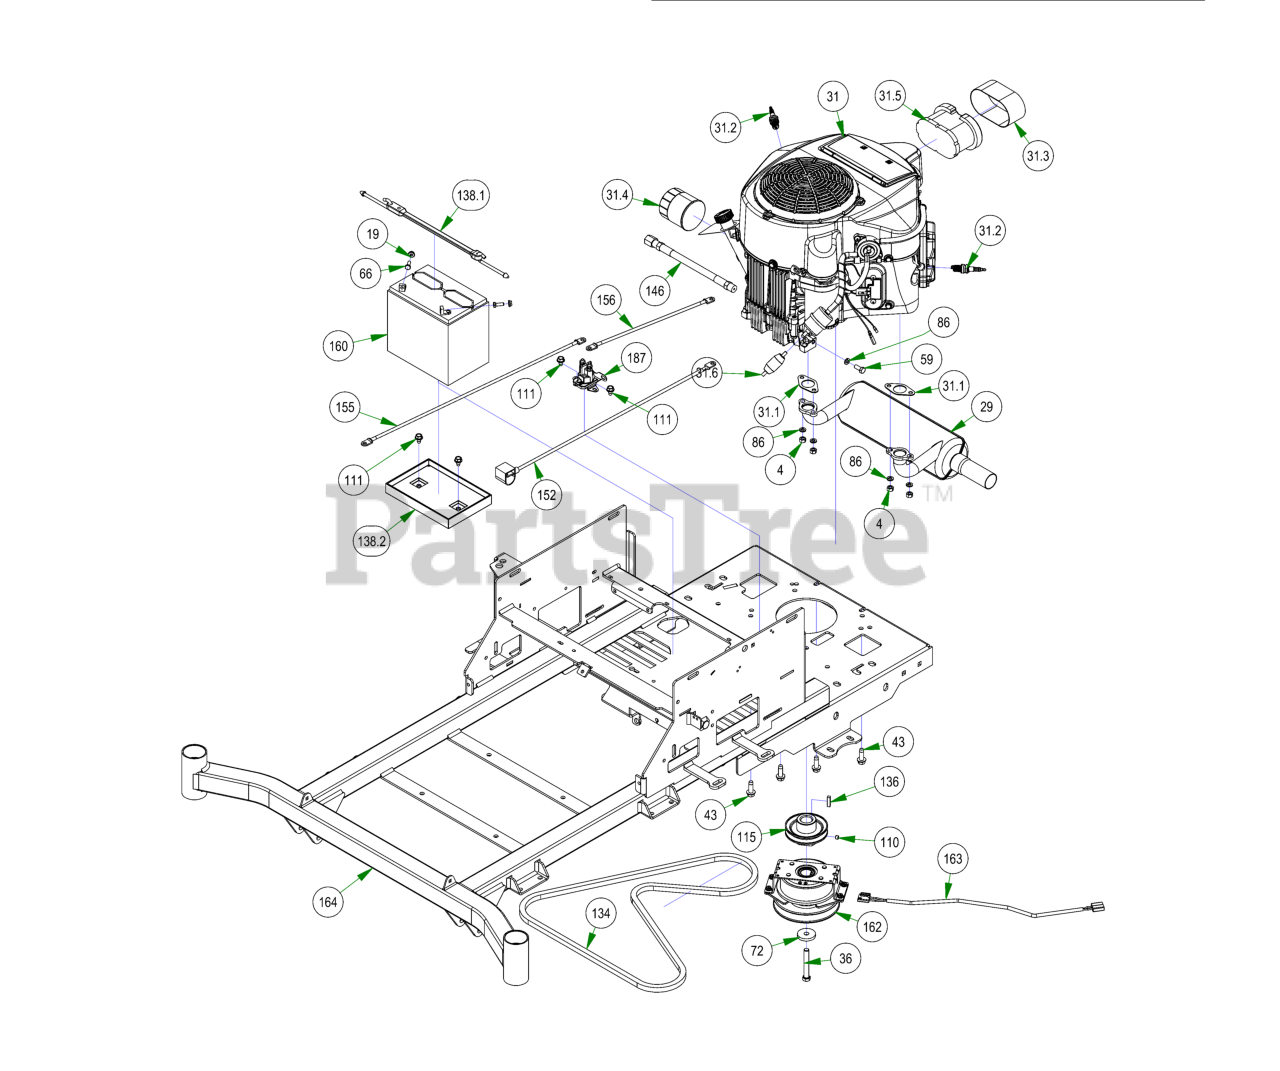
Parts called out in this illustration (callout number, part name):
4	M8-1.25 DIN 934 HEX NUT (CL.8) ZINC
19	1/4-20 HEX SERRATED FLANGE NUT HARD/ZINC
29	Kawasaki Muffler 1251
31	Kawasaki FR691 29.5HP
31.1	Exhaust Gasket
31.2	Spark Plug - Kawasaki
31.3	Air Filter Pre-Cleaner for KAW
31.4	22-26 Kaw Oil Filter FR Engine
31.5	Kawasaki Air Filter
31.6	Universal Inline Fuel Filter
36	7/16-20x3” Hex Bolt GR 8 W/ Patch
43	3/8-16 X 1-1/8 HEX WASHER UNSLOT SERRATED (TRI-LOB) TRS ZINC YELLOW
59	M8-1.25 X 20MM DIN 933 HEX TAP BOLT (CL 8.8) ZINC
66	1/4-20 X 3/4 HEX CAP SCREW (GR.5) ZINC
72	CLUTCH WASHER
86	5/16 SPLIT LOCKWASHER ZINC
110	5/16-24 X 1/4 SOCKET SET SCREW (CUP PT) PLAIN
111	5/16-18 X 1/2 HWH unslot (F) tcs zinc
115	3-3/4" Motor Pulley
136	1/4 X 1 SQ MACHINERY KEY 1018 STL PLN
138	2023 Battery Hold Down Assembly Strap
138.1	2023 Rubber Battery Hold Down Strap
138.2	Battery Tray
146	Oil drain Hose
152	24 inch Black Cable – MZ/ZT
155	24" Red Battery Cable
156	12 in red battery cable
160	SP-35 Battery
163	Clutch Pigtail
164	2023 MZ-Avenger 54-60 Frame - Painted
